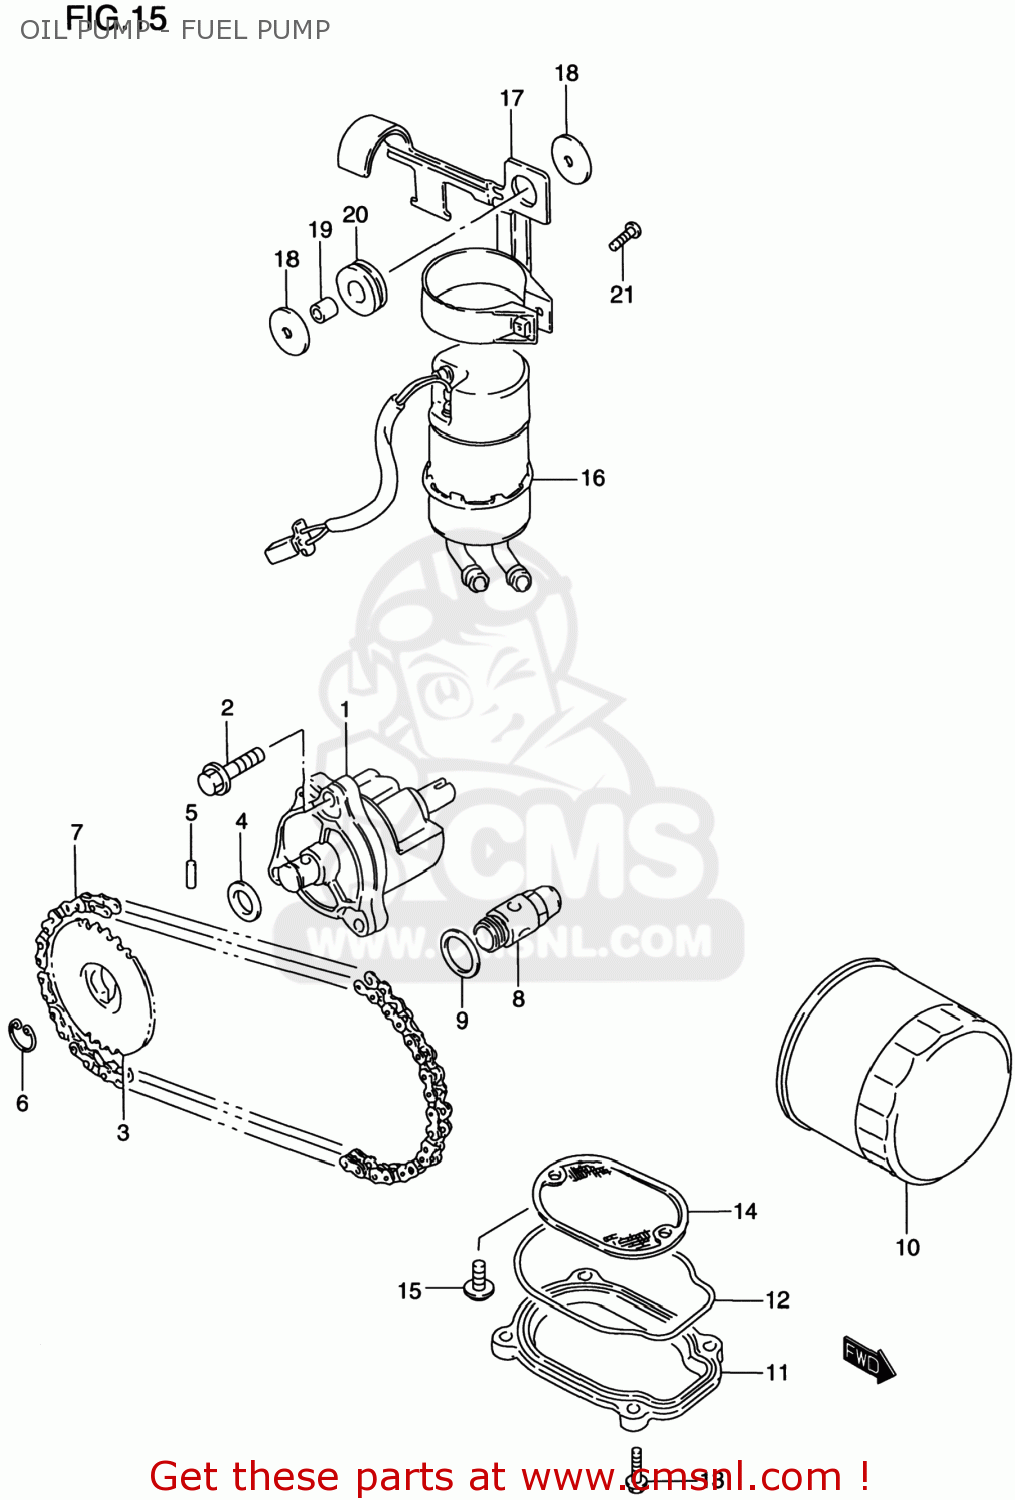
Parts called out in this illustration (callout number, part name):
1	PUMP ASSY,ENGINE OIL
2	BOLT
3	SPROCKET,OIL PUMP DRIVEN
4	SHIM(12X20X0.5)
5	PIN(5X18)
6	CIRCLIP,12 MM
7	CHAIN,OIL PUMP DRIVE
8	VALVE ASSY,OIL RELIEF
9	GASKET(16X22X2) (NAS)
10	FILTER ASSEMBLY,ENGINE OIL
11	CAP,OIL STRAINER
12	O RING,OIL STRAINER CAP
13	BOLT
14	STRAINER,ENGINE OIL
15	SCREW
16	PUMP ASSY,FUEL
17	BRACKET,FUEL PUMP
18	WASHER(6.5X24X1.6)
19	SPACER(6.5X10.5X6.5)
20	CUSHION
21	SCREW
